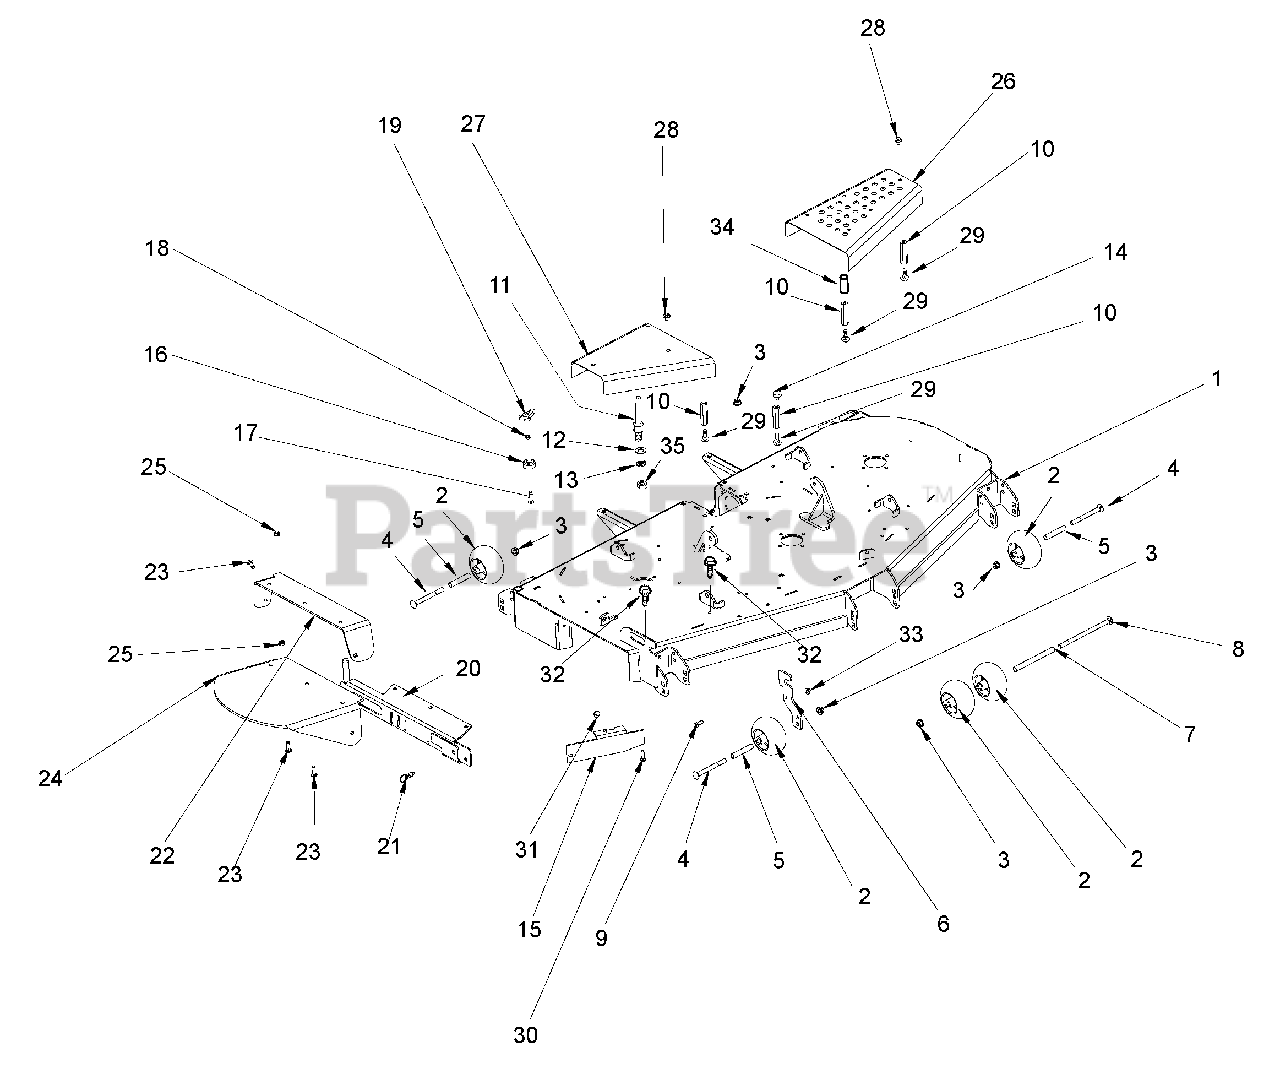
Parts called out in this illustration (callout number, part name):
1	Weldment, 72" Side Discharge Deck (OFM)
2	Wheel, Antiscalp
3	Nut .50-13 Nyloc Flange
4	Bolt, Round Head Square Neck .50-13 x 5.00 YZ
5	Spacer, .510 x .625 x 3.35
6	Chute Storage Bracket- Red
7	Spacer, .510 x .625 x 6.70
8	Bolt, Round Head Square Neck .50-13 x 8.50
9	Bolt, Hex .38-16 x 1.00
10	Nut, Coupling .31-18 x 3.00
11	Stud, Deck Stop
12	Washer, Flat Steel .656 x .31 x .095
13	Washer, Locking .62 x .156
14	Bumper, Rubber
15	72" Discharge Baffle - Red
16	Bumper, Recessed 1.50 x .63
17	Bolt, Round Head Square Neck .31-18 x 1.50 Grade 5
18	Nut, Locking-Center .31-18
19	Knob, Clamping .312-18 Nyloc
20	72" Discharge Chute Mounting Weldment - Red
21	Pull Pin, .50-13 Thread x .310 Diameter Plunger
22	Rubber Discharge Chute Support-Red
23	Bolt, Round Head Square Neck .38-16 x 1.25 Grade 5
24	Chute, Rubber Discharge
25	Nut, .38-16 Nyloc Flange
26	Guard, 72" Left Hand Spindle
27	Guard, 72" Right Hand Spindle
28	Bolt, SEMS .31-18 x .62
29	Bolt, Round Head, Square Neck .31-18 x .75 Loctite
30	Bolt, Round Head Square Neck .31-18 x 1.00 Grade 5
31	Nut, Nyloc Flange .31-18
32	Screw, Tapping .38-16 x .50
33	Nut, Center Lock .38-16
34	Hose, .88ID x 1.25OD x 2.50 PVC
35	Nut, Hex - Slotted .625-18
